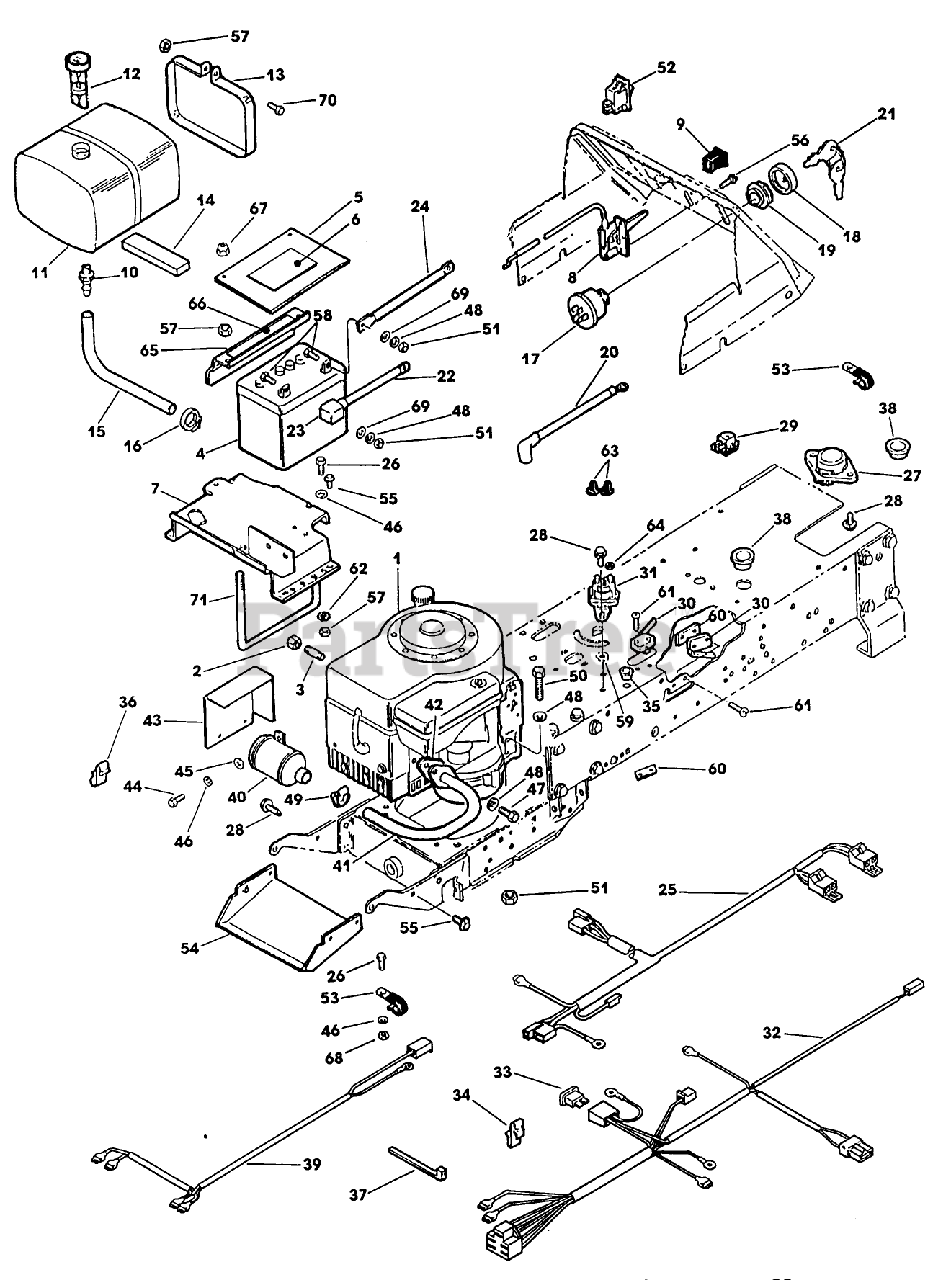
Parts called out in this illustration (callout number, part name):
5	BATT. CVR & R/B 744648
9	THROTTLE KNOB
12	FUEL CAP&GUAGE AY.
15	HOSE
18	BEZEL
19	NUT
21	KEY
22	CABLE ASSEMBLY
27	SWITCH,SEAT
29	SWITCH
30	SWITCH
31	SOLENOID
36	CLIP-RETAINER, WIRE
40	MUFFLER AY
42	GASKET
44	SCREW
51	NUT SS
52	SWITCH ASSEMBLY
58	SCREW - HEX
64	NUT-HEX
65	HOLD DOWN & DECAL (12)
67	NUT-LOCK, CONE
68	NUT
